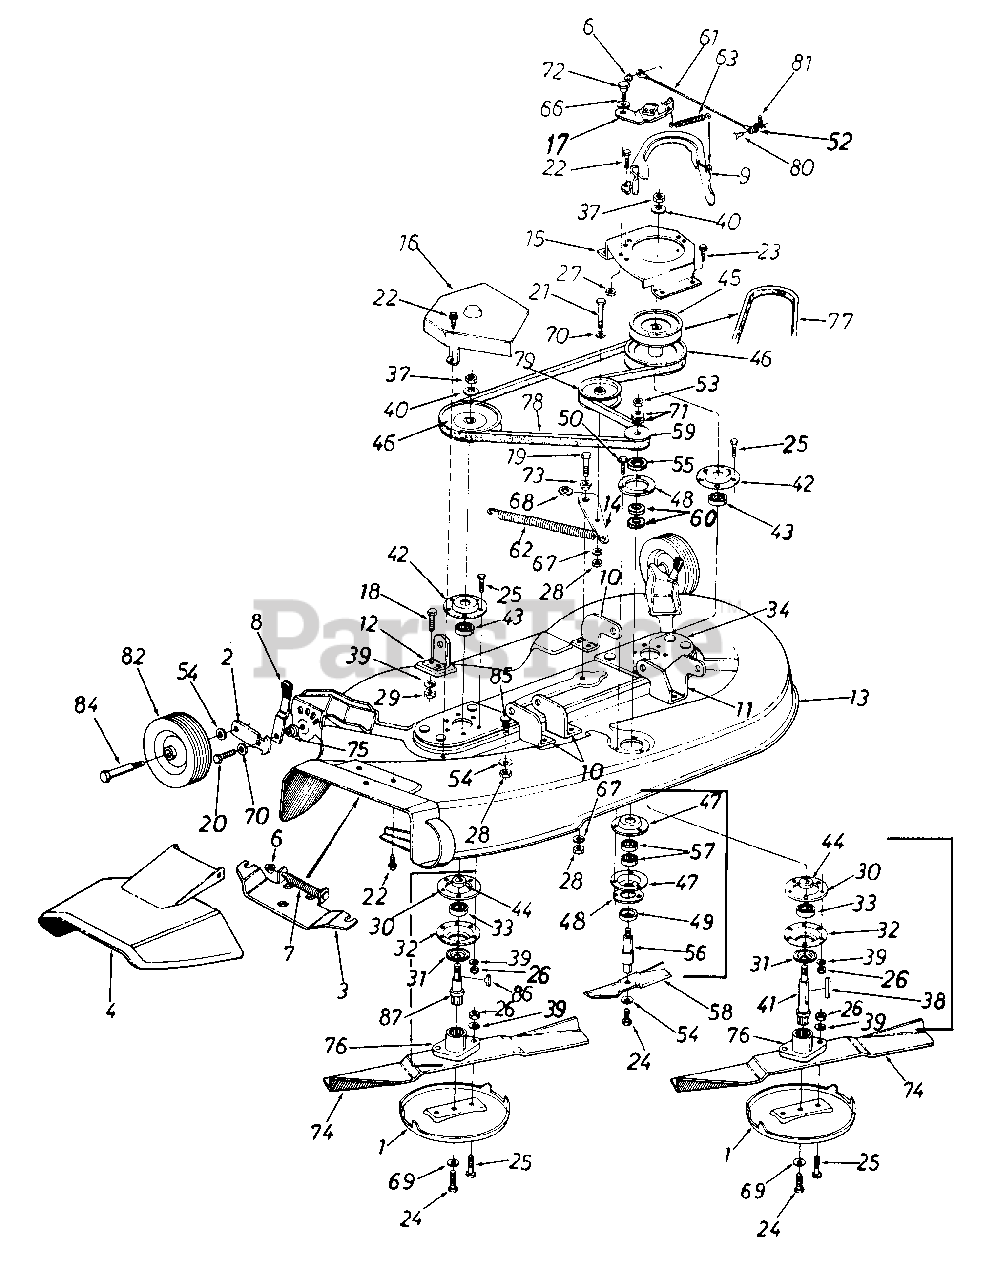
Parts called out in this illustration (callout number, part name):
1	Anti-Scalp Plate
2	Bar-Wheel Pivot
3	Adapter Plate
4	Chute Cover Ass'y.
6	Cap Speed Nut 1/4" Rod
7	Torsion Spring
8	Spring Lever Ass'y.
9	Belt Guard
12	Deck Hanger Bracket
13	44" Deck Ass'y.
14	Idler Bracket
15	Pulley Cover L.H.
18	Hex Bolt 5/16-18 x .75" Lg.*
19	Hex Bolt 3/8-24 x 1.00" Lg.*
20	Hex Bolt 3/8-24 x 1.25" Lg.*
21	Hex Bolt 3/8-24 x 1.50" Lg.*
22	Hex Wash. S-Tapp Scr. 1/4-20 X .50
23	Hex Wash. Hd. Tapp Scr. 5/16-18 x .75" Lg.
24	Hex Cent. L-Bolt 3/8-24 x .88" Lg.
25	Hex Bolt Special 5/16-24 x 1.0" Lg.
26	Hex Nut 5/16-24 Thd.*
27	Hex Cent. L-Nut 5/16-18 Thd.
28	Hex Nut 3/8-24 Thd.*
29	Hex Nut 5/16-18 Thd.*
30	Reinforcement Plate
31	Bearing Shield
32	Open Brg. Housing 1.85 I.D.
33	Ball Brg. .787" I.D. x 1.85" O.D. x .551
34	Spindle Mounting Plate Ass'y.
37	Hex Jam Nut 5/8-18 Thd.*
38	Sq. Key 3/16" x 2.25" Lg.
39	L-Wash. 5/16" I.D.*
40	Bell-Wash. .630" I.D. x 1.25" O.D.
41	44" Deck Blade Spindle
42	Bearing Housing 1.85" I.D.
43	Ball Brg. .787" I.D. x 1.85" O.D. x .551
44	Spacer 1.0" O.D. x .790" I.D.
45	5/8 "V"-Pulley .79" I.D. x 5.75" O.D.
46	"V"-Pulley .79" I.D. x 6.50" O.D.
47	Bearing Housing 1-3/8" I.D.
48	Reinforcement Plate
49	Bearing Shield
50	Hex Wash. Hd. B-Tap Scr. 1/4 X .75" Lg.
52	Fl-Wash. .20" I.D. x .62" O.D.
53	Hex Jam Nut 1/2-20 Thd.
54	Bell-Wash. .400" I.D. x .88" O.D.
55	Fl-Wash. .635" I.D. x 1.04" O.D.
56	6.5" Blade Spindle
57	Ball Brg. .62" I.D. x 1.38" O.D. x .44
59	1/2" "V"-Pulley Half .625" I.D. x 2.25" O.D.
60	Fl-Wash. 5/8" I.D. x 15/16" O.D.
61	Brake Cable 11.75" Lg.
62	Extension Spring .73" O.D. x 4.31 " Lg .
63	Ext. Spring .50" x 2.51" Lg.
66	Spring Wash. .445" I.D. x .75" O.D.
67	L-Wash. 3/8" I.D.
68	Spring Wash. .625" I.D. x .885" O.D.
69	L-Wash. 3/8" I.D. (Heavy Duty)
70	Bell-Wash. .400" I.D. x 1.13" O.D.
71	Bell-Wash. .505" I.D. x 1.00" O.D.
72	Shld. Bolt .437" Dia. x .180
73	Shld. Spacer .625" I.D.
75	Shld. Spacer
76	Blade Adapter
77	"V"-Belt 1/2" X 52.0" Lg.
78	"V"-Belt 1/2" X 74.0" Lg.
79	Fl-ldler w/ Flanges 3.50" O.D.
80	Clevis Pin 1/4" Dia. x .53" Lg.
81	Intern. Cotter Pin 5/16" Dia.
82	Deck Wheel 6.0" x 1.38
84	Shld. Bolt 3/8-16 x 1.41
85	Rib Neck Bolt
86	Sq. Key 3/16" x 3/16" x .75" Lg.
87	44" Deck Blade Spindle
